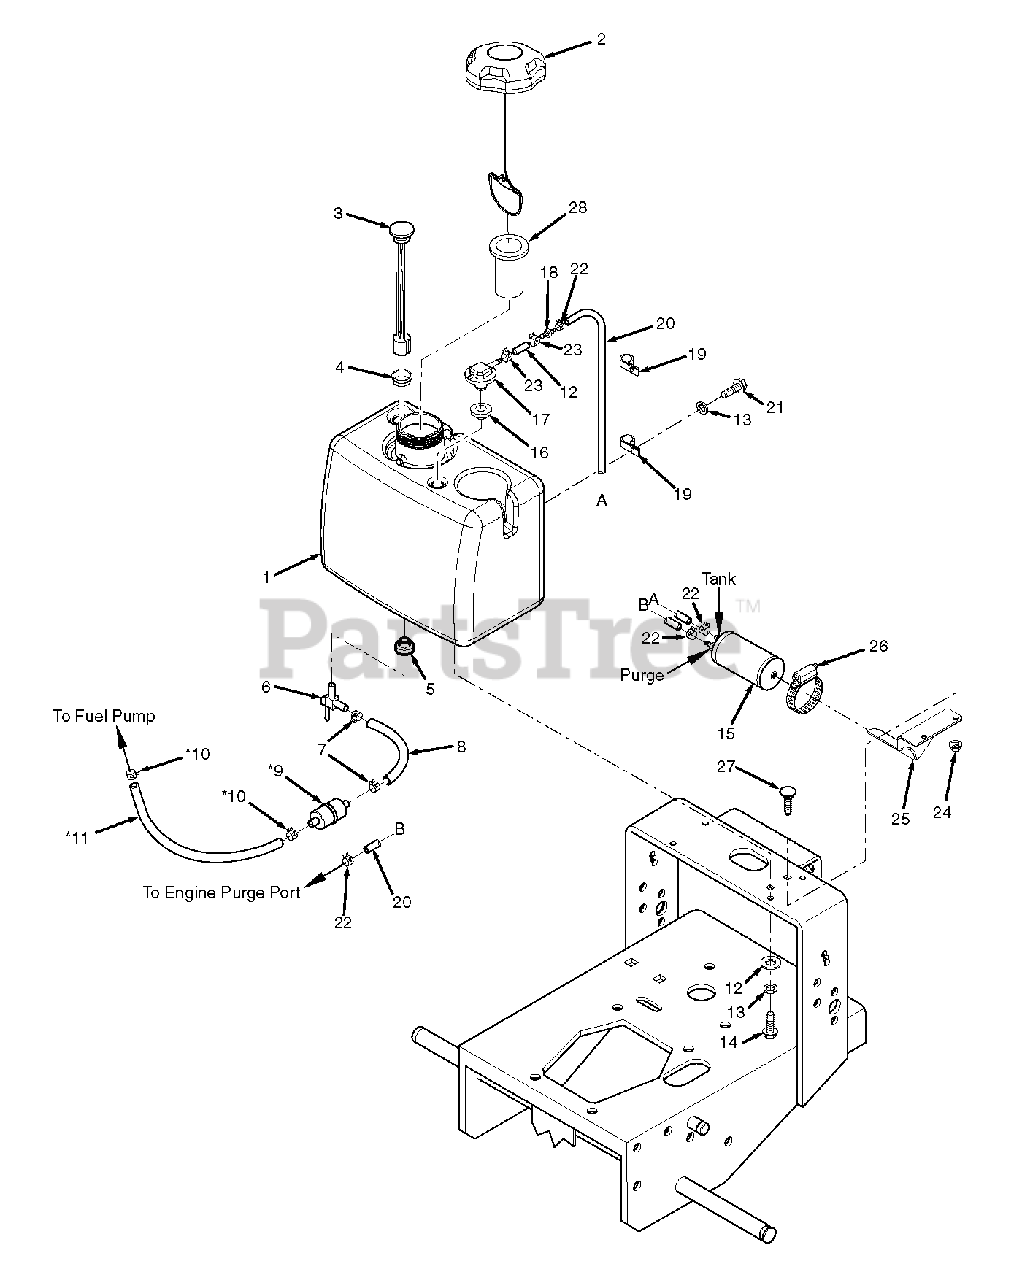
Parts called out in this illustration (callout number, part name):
1	Fuel Tank Assembly
2	Fuel Cap w/ Tether
3	Fuel Gauge Assembly
4	Seal, Fuel Gauge
5	Bushing, .56 Dia. Viton
6	Ball Valve w/Screen
7	Clamp, Fuel Hose
8	Fuel Hose, 1/4" ID (order by inch)
9	Fuel Filter
10	Clamp, Fuel Hose
11	Fuel Hose
12	Hose, Vapor Recovery 1/4" (order by inch)
13	Lockwasher, 5/16" Spring
14	Bolt, Hex Head 5/16-18 x 1"
15	Carbon Canister
16	Grommet, Viton,
17	Fitting, Remote Vent
18	Mender, 1/4 x 3/16 w/.02 Hole
19	Clamp, 3/8"
20	Hose, Vapor Recovery 3/16" (order by inch)
21	Bolt, Hex Head 5/16-18 x 3/4"
22	Clamp, Vapor Recovery Hose 3/16"
23	Clamp, Fuel Hose 7/32" ID
24	Nut, Serrated Flange 5/16-18
25	Bracket, Canister Mounting
27	Bolt, Carriage 5/16-18 X 1"
28	Tube, Fuel Tank Insert - 4"
